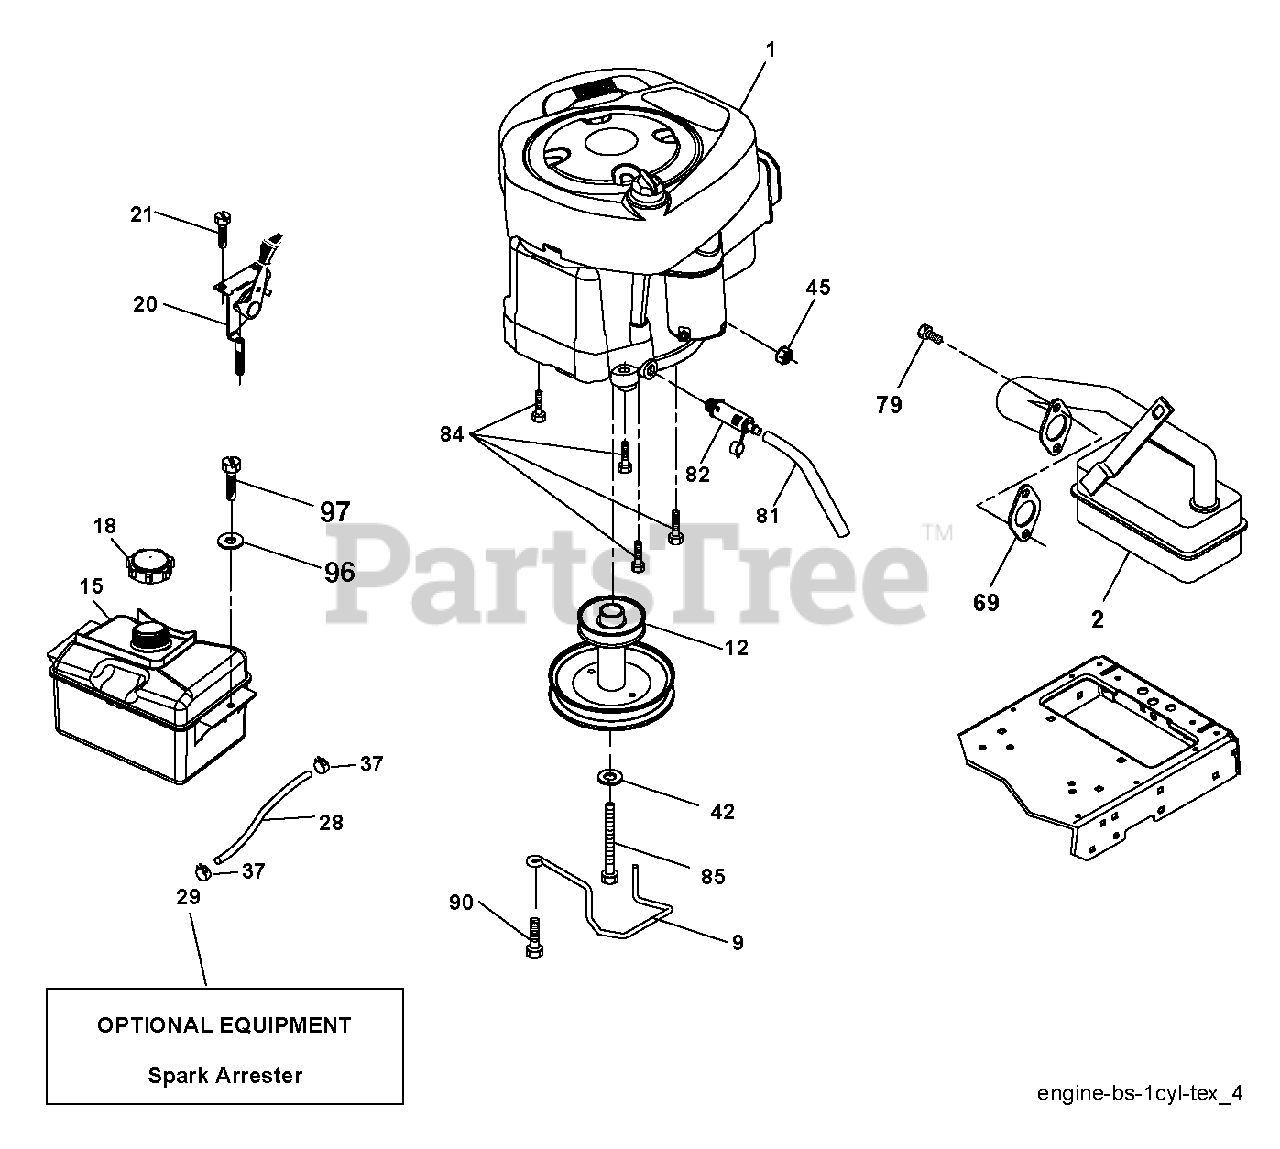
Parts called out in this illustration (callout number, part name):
2	MUFFLER.B&S.MODEL.21.11HP.OHV
9	KEEPER.BELT.ENGINE.3.25 (3 2)
12	PULLEY ENGINE
15	RP TANK FUEL FRT 1.5 GAL
18	FUEL CAP
20	CONTROL.TH/CK.C.
21	SCREW.#10 X 0.750.BOS
28	LINE.FUEL.20"FRONT.EMI
29	KIT.SPARK ARRESTOR 794945 B&S
37	HOSE CLAMP
42	LOCKWASHER
45	NUT
69	REPL BY 532 27 22-93
79	SCREW.SOCKET HD.5/16-1
81	TUBE, DRAIN OIL ASM.
82	PLUG DRAIN OIL EASY
84	SCREW.3/8-16
85	BOLT HEX 7/16-20X4-1/4"
90	SCREW 3/8-16X1
97	SCREW HEXWSHR 1/4-20X3/4
